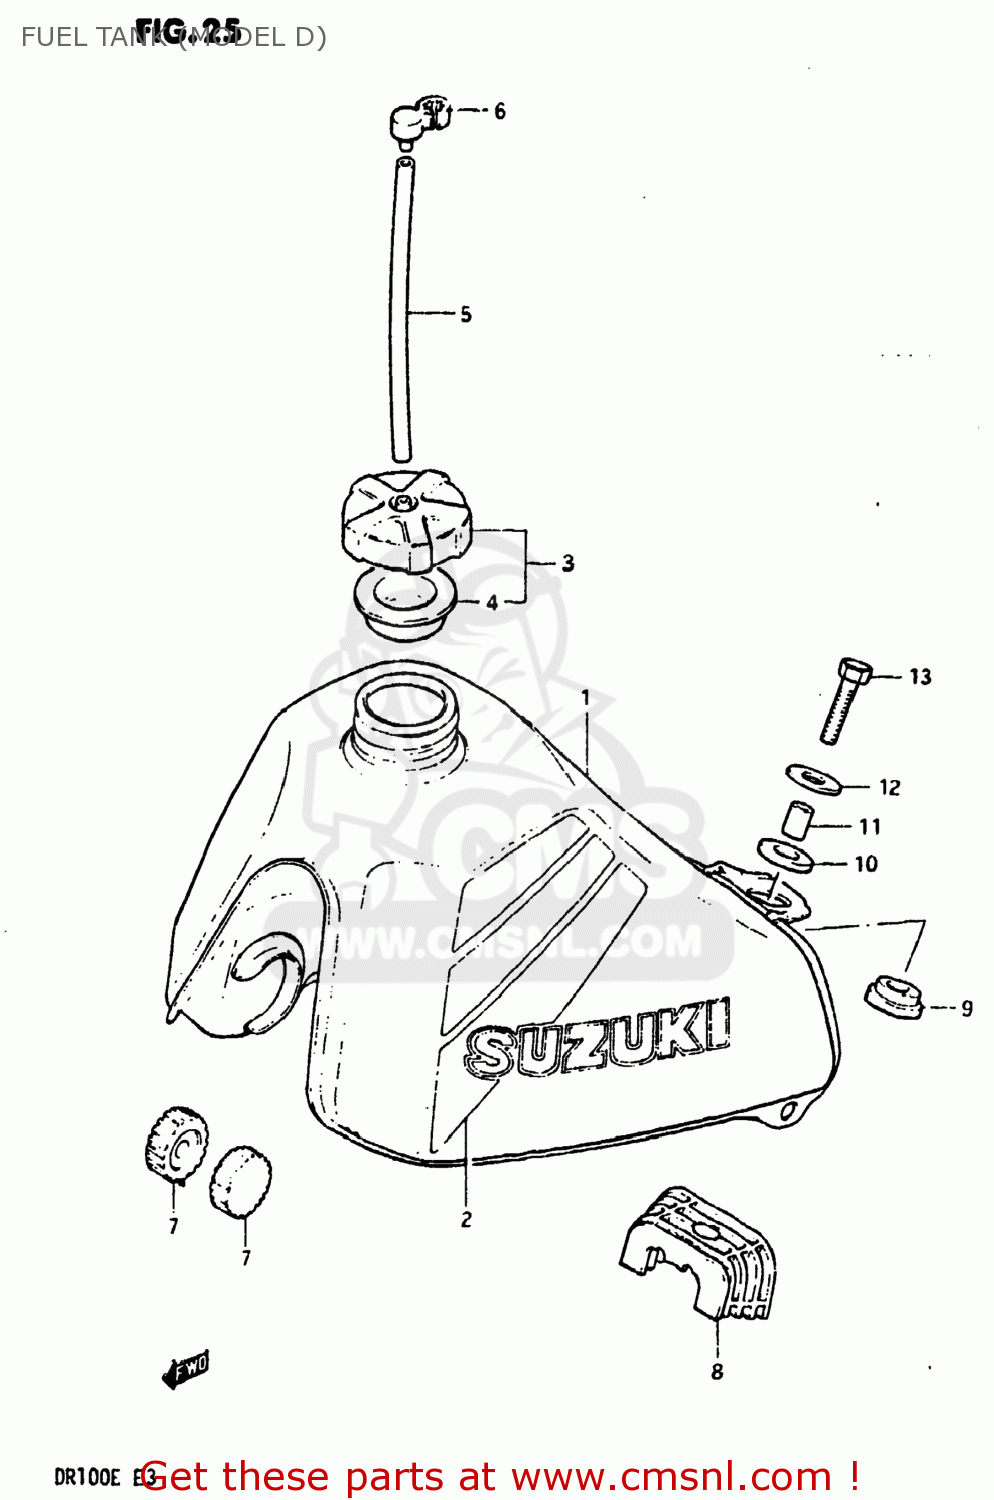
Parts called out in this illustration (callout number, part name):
1	TANK ASSEMBLY,FUEL
2	TAPE SET,FUEL TANK
3	CAP SET,FUEL TANK
4	GASKET (NAS)
5	HOSE
6	CLAMP,FUEL TANK BREATHER HOSE
7	CUSHION
8	CUSHION,FUEL TANK
9	CUSHION
10	CUSHION
11	SPACER(8.5X12X19)
12	WASHER (8.5X29X1.6)
13	BOLT (8X30)
